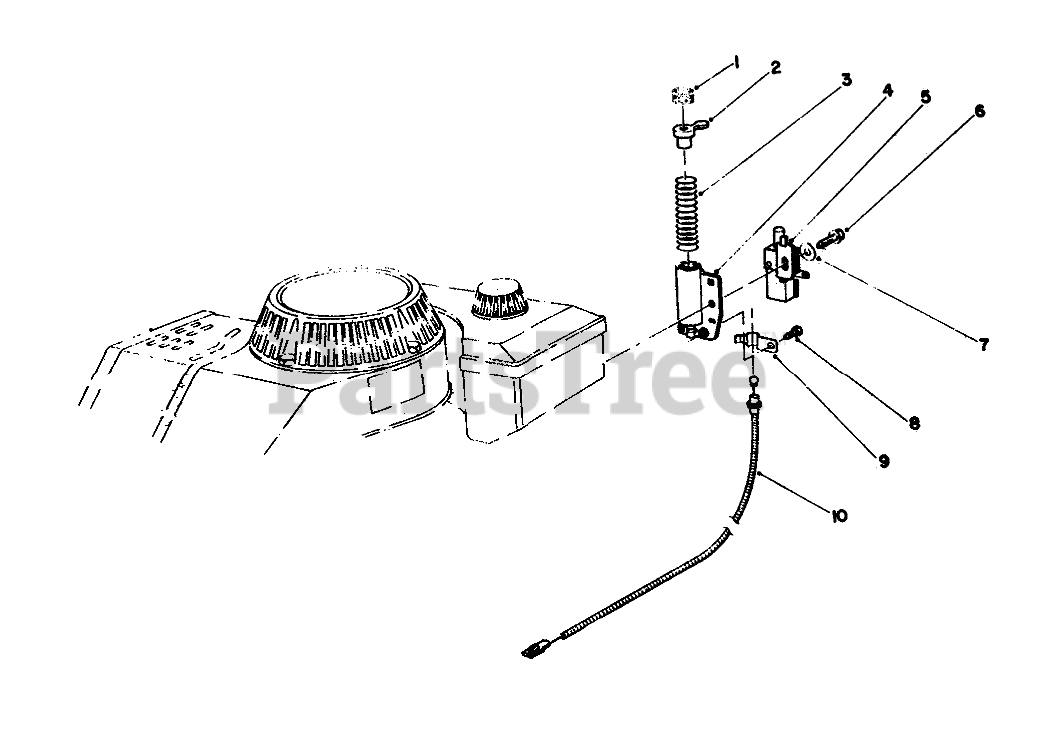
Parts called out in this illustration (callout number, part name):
1	Pad-Friction
2	Plunger & Pad Assembly (Incl. Ref. #1)
3	COMPRESSION SPRING
4	TUBE W A
5	PUSH BUTTON SWITCH
6	THO FORM SCREW M6 X 1
7	WASHER-FLAT
8	SCREW
9	CABLE CLAMP
10	BRAKE CABLE
